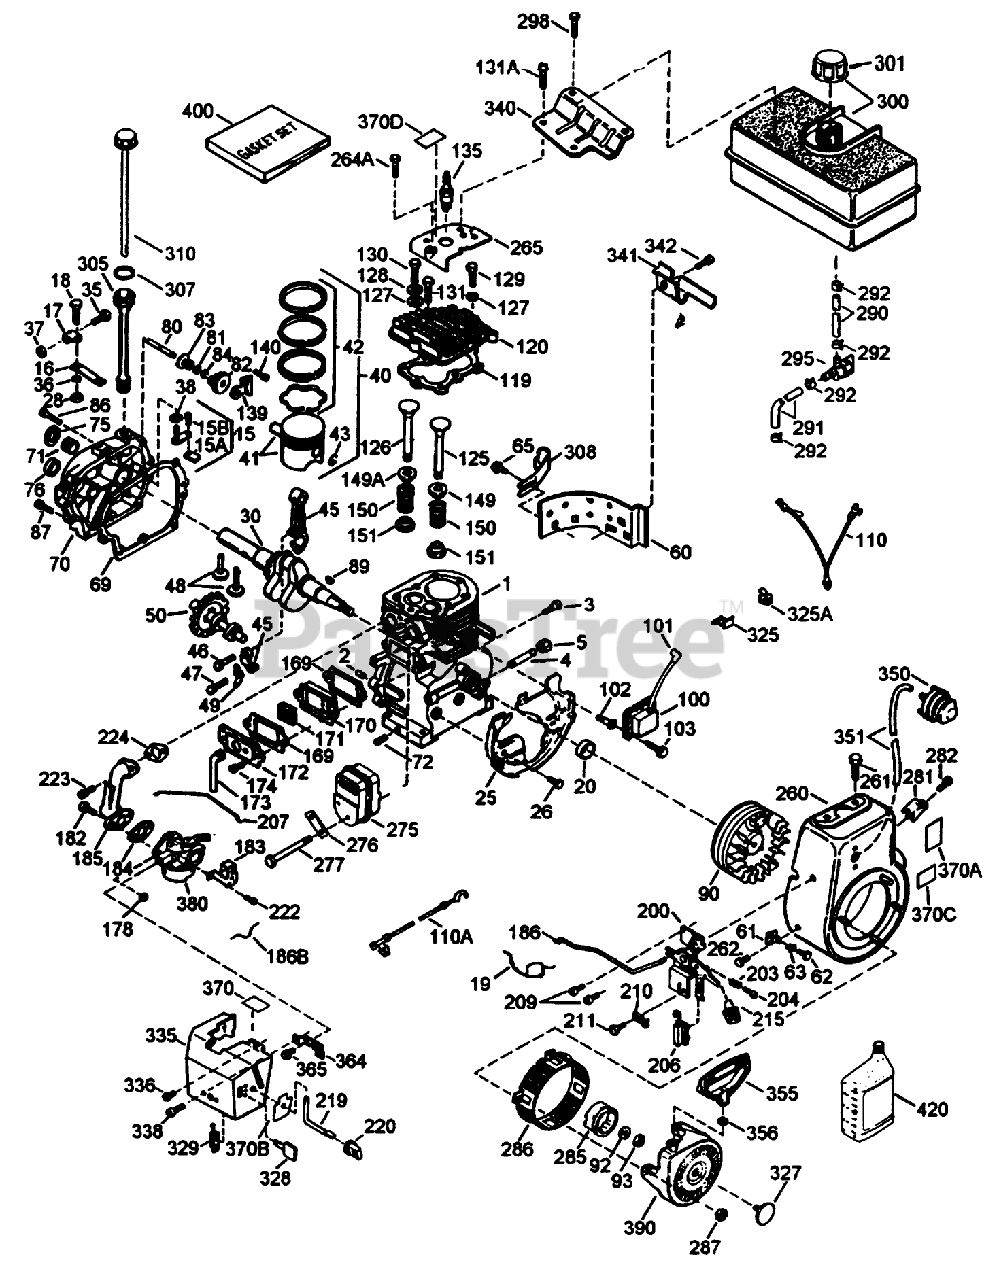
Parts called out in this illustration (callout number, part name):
1	Cylinder (Incl. ref. #2 20)
2	Pin-Dowel
3	Screw (1/4-20x1/2)
4	Nipple-Pipe
5	Cap-Pipe
15	Rod, Governor (Incl. Nos.62 63)
15A	Yoke-Governor
15B	Screw (6-40x5/16)
16	Lever-Governor
17	Clamp-Lever, Governor
18	Screw
19	Spring-Throttle
20	Seal-Oil
25	Baffle-Housing, Blower
26	Screw (1/4-20x19/32)
28	Nut-Lock
30	Crankshaft
35	Screw
36	Washer-Lock
37	Nut-Lock
38	Ring-Retaining
40	Piston, Pin Ring Assy. Std.(Includes ref. #41, 42 43)
41	Piston Pin Assembly Standard (Includes ref. #43)
42	Ring Set (STD)
43	Retaining Ring-Piston Pin
45	Rod Assembly-Connecting (Incl. ref. #46, 47 49)
46	Bolt-Rod
47	Bolt-Rod
48	Lifter-Valve
49	Dipper-Oil
50	Camshaft (MCR)
60	Extension-Housing, Blower
61	Bracket
62	Screw (8-32 x 3/8)
63	Grommet
65	Screw
69	Gasket-Cover, Cylinder
70	Cover-Cylinder (Includes 71, 75, 80)
71	2025A77 WIZARD ROTA
75	Seal-Oil
80	Shaft-Governor
81	Washer-Flat
82	Gear Assy., Governor (Incl. Ref. #45)
83	Spool-Governor
84	Ring-Retaining
86	Screw (1/4-20x1-3/16)
87	Screw (1/4-20x1-11/16)
89	Key-Flywheel
90	Flywheel ASM
92	Washer-Belleville
93	Nut-Flywheel
100	Solid State ASM
101	Cover-Spark Plug
103	Screw (T-15, 10-24 x 15/16)
110	Ground Wire
119	Gasket-Head, Cylinder
120	Head-Cylinder
125	Valve, Exhaust (Standard)(Incl. No. 9)
126	Valve, Intake (Std.) (Incl. Ref. #58)
127	Washer-Flat
128	Washer-Belleville
129	Screw (5/16-18x1-25/32)
130	Screw (5/16-18x1-1/2)
131	Screw (5/16-18 X 2)
131A	Screw
135	Spark Plug-Resistor (R J19 L M)
139	Bracket-Gear, Governor
140	Screw (10-24x1/2)
149	Cap-Spring, Valve
149A	51106 GILSON ROTARY
150	Spring-Valve
151	Keeper-Spring, Valve
169	Gasket-Cover, Valve
170	Body-Breather
171	Element-Breather
172	Cover-Valve
173	Tube-Breather
174	Screw
178	Nut and Lock Washer (1/4-28)
182	Screw (1/4-28x1)
183	Bracket-Choke
184	Gasket-Carburetor To Intake Pipe
185	Pipe-Intake
186	Link-Governor
186B	Spring-Choke
200	Bracket-Control (Includes 19, 203, 204, 206)
203	Spring-Compression
204	Screw
206	Terminal
207	Link-Throttle
209	Screw (10-32 x 1/2)
215	Knob-Control
219	Rod-Choke
220	Knob-Control
222	Screw (10-32 x 1/2)
223	Screw (T-30, 5/16-18x1-3/32)
224	Gasket-Pipe, Intake
260	Housing-Blower
261	Screw (5/16-18x3/4)
262	Screw
264A	Screw (1/2-20x5/8)
265	Cover-Cylinder Head
275	Muffler
276	62513 SNWTHWR W/284
277	Screw (5/16-18x4-3/16)
281	Screw
282	Screw (8-32 x 3/8)
285	Cup-Starter
286	Screen-Starter
287	Nut and Lock Washer (1/4-28)
290	Line-Fuel (8.62)
291	Line-Fuel
292	Clamp-Line, Fuel
295	Valve-Shut Off, Fuel
298	Screw (1/4-15x7/8)
300	Tank-Fuel (Includes 292, 301)
301	Cap-Fuel
305	Tube-Fill, Oil
306	O-Ring
308	Clip-Tube, Fill
310	Gauge Oil ASM
314	Screw (1/4-20 x 3/4)
316	Coil-Alternator, 18 Watt (Includes 323)
323	Terminal
325	Clip-Wire
327	Plug Starter
335	Cover-Carburetor
336	Screw (10-32x1/2)
338	Screw (10-32 x 3/8)
340	Bracket-Tank, Fuel
341	Bracket-Tank, Fuel (Black)
342	Screw (1/4-20x19/32)
350	Primer-Asm
351	Line-Primer
355	Handle-Starter, Mitten Grip
364	Bracket-Carburetor
365	Screw (8-32x27/64)
380	Screw-Hex Washer Hd.
390	Rewind Starter
400	Gasket Set
421	Oil-Engine (SAE 5W30)
